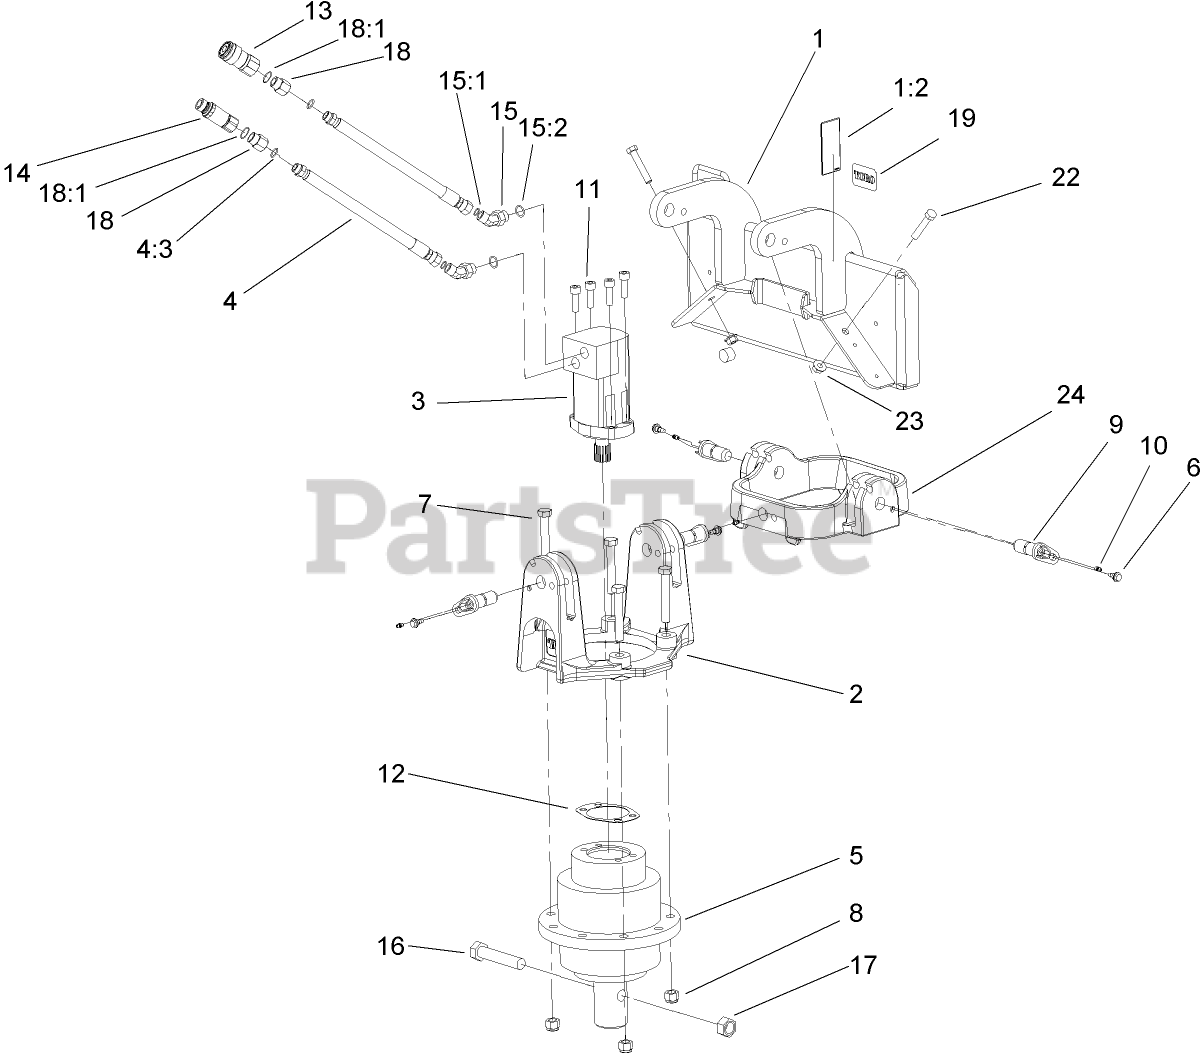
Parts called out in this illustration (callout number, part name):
1	AUGER MOUNT ASM
1:2	DECAL-DANGER
3	HYDRAULIC MOTOR ASM
4	HYD HOSE ASM
4:3	O-RING
5	DRIVE-PLANETARY
6	BOLT-SHOULDER
7	SCREW-HH
8	NUT-LOCK, NI
9	PIN-PIVOT
10	FITTING-GREASE
11	SCREW-HSH
12	GASKET
13	COUPLER-FACE, FLUSH
14	NIPPLE-CONNECT, PRESSURE
15	FITTING-HYD, 45 DEG
15:1	O-RING
15:2	O-RING
16	SCREW
17	NUT-HEX
18	ADAPTER-HYD
18:1	O-RING
19	DECAL
22	SCREW-HH
23	NUT-HHF
